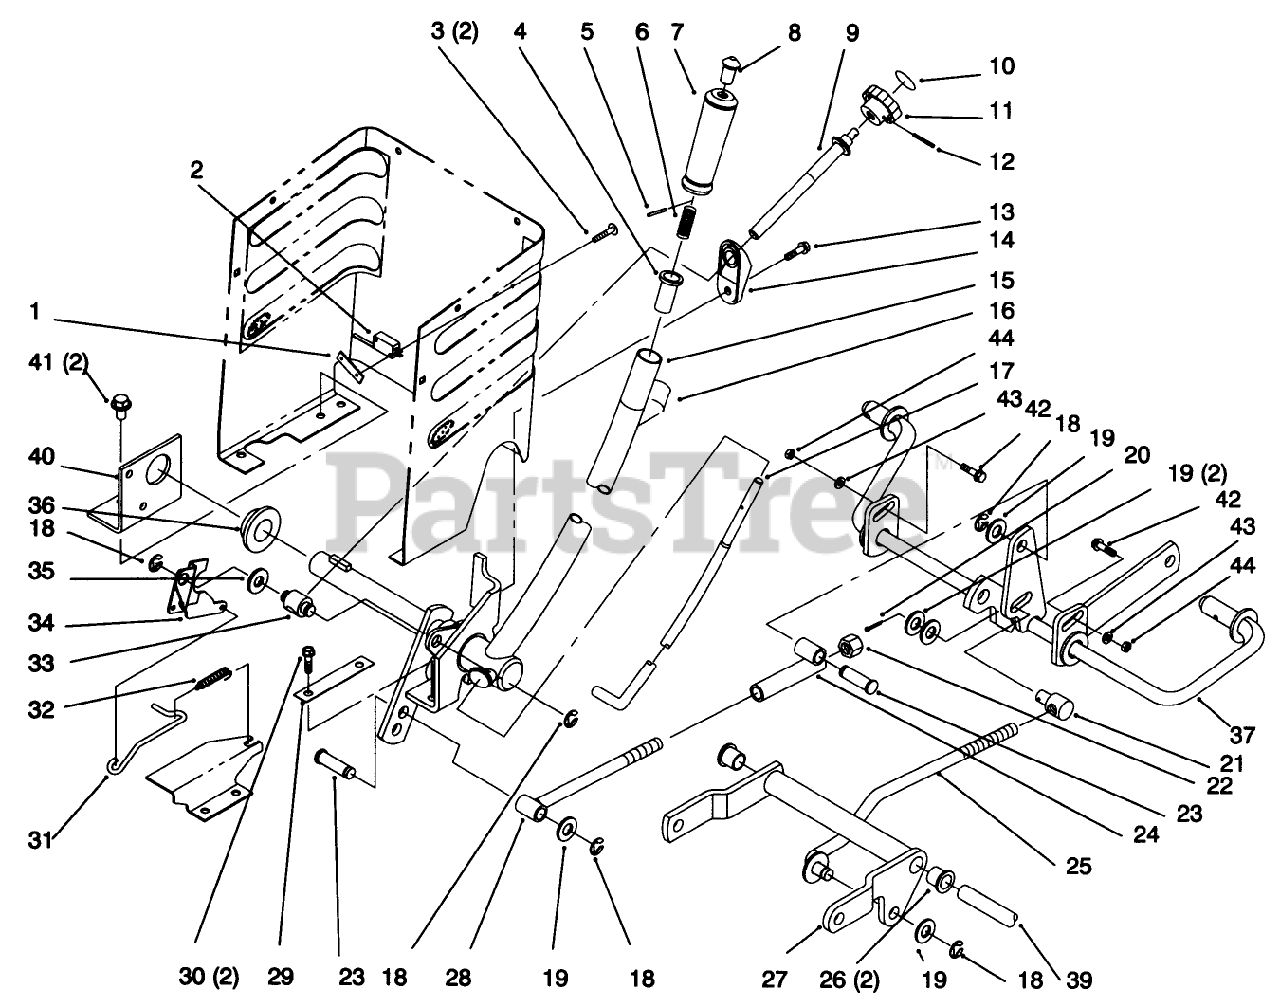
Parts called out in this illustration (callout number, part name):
1	NUT-SPEED
2	SWITCH-MICRO
4	RETAINER-SPRING
5	PIN-SPIROL
6	SPRING-COMPRESSION
7	GRIP-HANDLE
8	TIP-ROD
12	PIN-SPIROL
13	SCREW-HWH
14	WEDGE - HOC
16	DECAL-LIFT
17	ROD-LEVER, LIFT
18	RING-RETAINING, EXTERNAL
19	WASHER-FLAT
20	PIN-COTTER
22	NUT-LOCK, NI
26	BUSHING-FLANGE
27	ARM-PIVOT
30	SCREW-HWHTF
31	ROD - HOC INDICATOR
32	SPRING - EXTENSION
34	PLATE - HOC GAGE
35	WASHER
36	BEARING-FLANGE
37	SHAFT-GAGE
39	SHAFT
41	SCREW-HWHTF
42	BOLT-CARR
43	WASHER-FLAT
44	NUT-LOCK, NI
